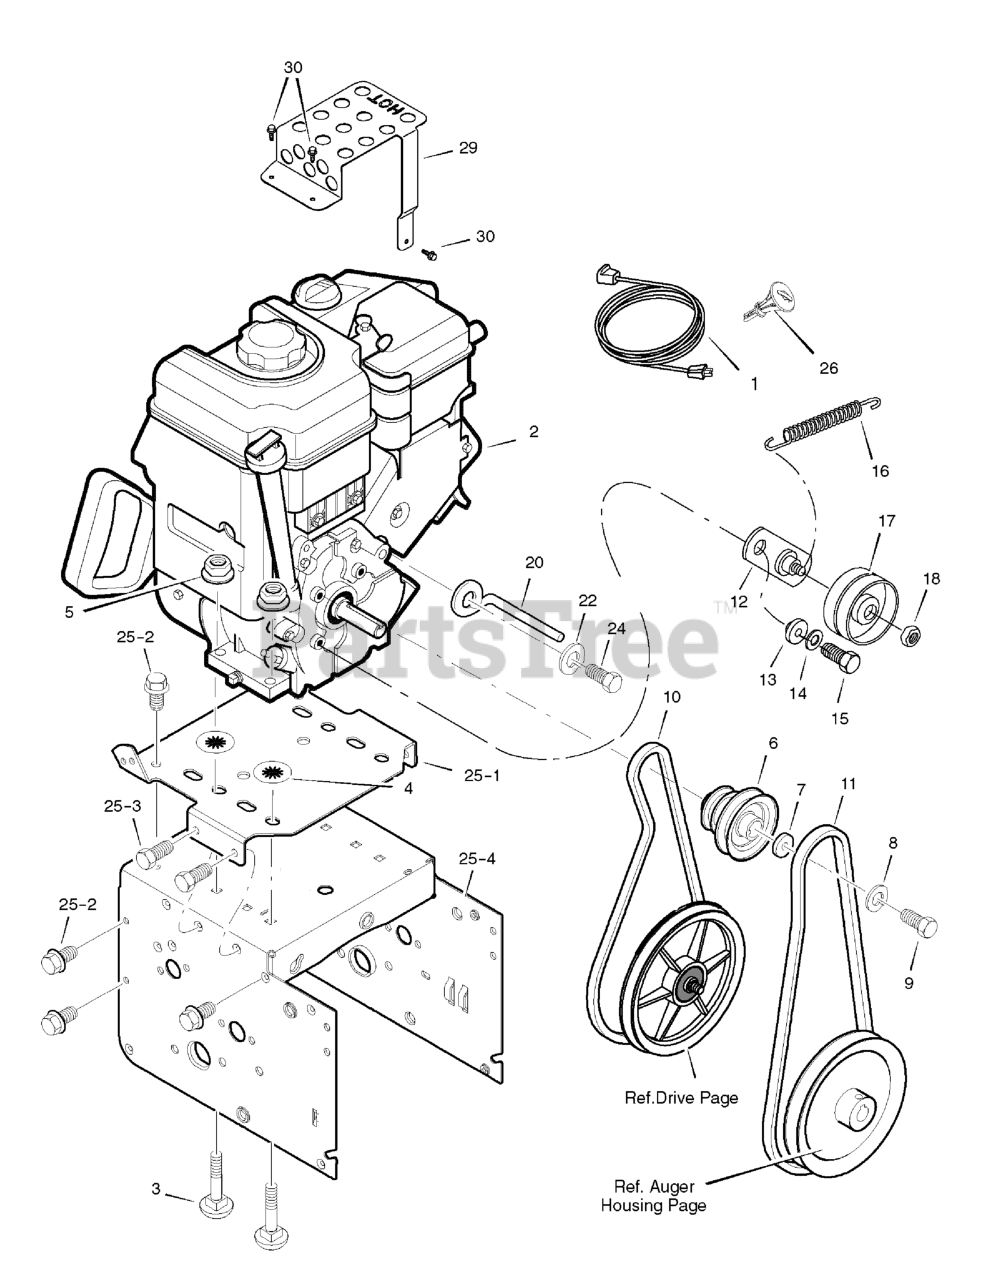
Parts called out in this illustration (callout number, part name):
1	CORD, Electric, 10FT. 110V
2	ENGINE
3	BOLT, Carriage, 5/16-18
4	RETAINER, Push
5	NUT, 5/16-18
6	PULLEY, Engine
7	WASHER
8	WASHER, 3/8
9	SCREW, 3/8-24 x 1
10	BELT, V 3L
11	BELT, V 4L
12	BRACKET ASSEMBLY, Idler
13	BUSHING, Idler Bracket
14	WASHER, SPLIT
15	SCREW, 5/16-24 x 3/4
16	SPRING, Idler Traction Drive
17	PULLEY, Idler
18	NUT, Jam, 3/8-16
20	GUIDE, Belt
22	WASHER, 5/16
24	SCREW, 5/16-24 x 3/4
25-1	PLATE, Engine Mount
25-2	SCREW, Tap, 1/4-20 x 5/8
25-3	SCREW, Tap, 5/16-18 x 1/2
25-4	FRAME, Motor Box
26	KEY, Briggs Engine
29	HEAT SHIELD, Muffler
30	SCREW, Hex-Washer
